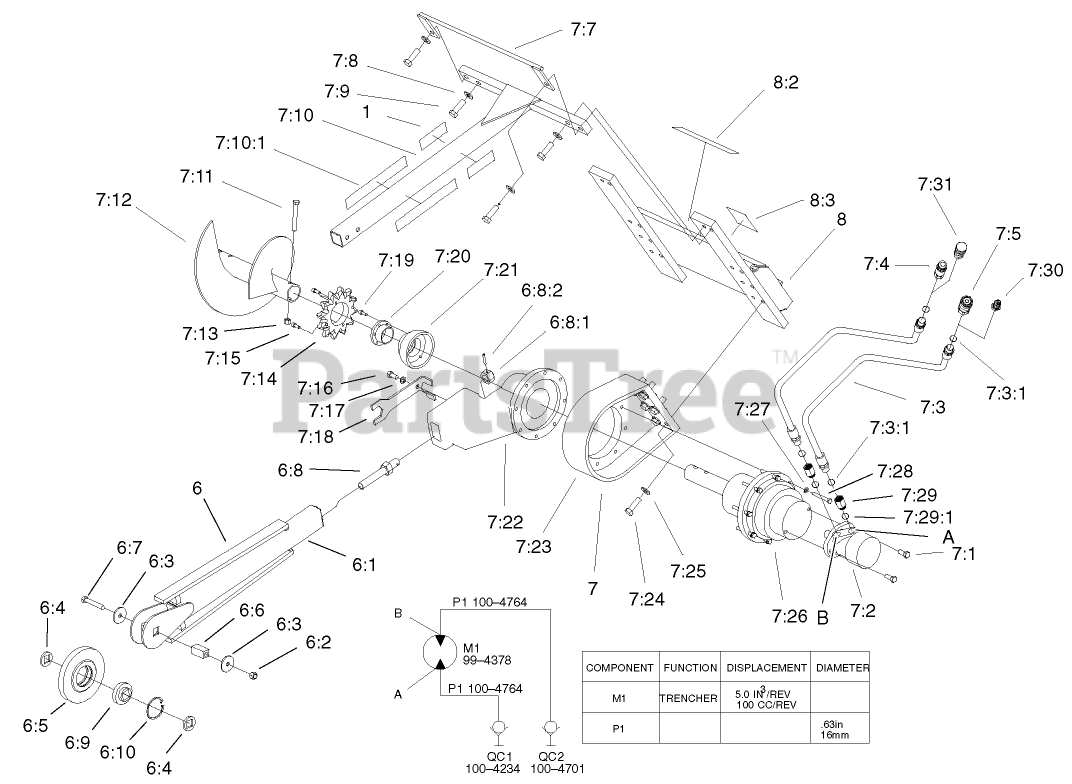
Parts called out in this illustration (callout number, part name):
1	DECAL-ATTACHMENT, DINGO
6	TRENCHER BOOM ASM
6:1	Boom ASM
6:2	NUT-LOCK
6:3	WASHER-ROLLER
6:4	SPACER-ROLLER
6:5	ROLLER-NOSE
6:6	PIN-ROLLER
6:7	SCREW-HH
6:8	ADJ SCREW ASM
6:8:1	NUT-HEX
6:8:2	PIN-ROLL
6:9	BEARING
6:10	RING-INT
7	Trencher Head ASM
7:1	SCREW-HH, LH
7:2	MOTOR-HYD(OPTIONAL), 100CC-1 INCH SHAFT
7:2	MOTOR-HYD, 80CC (1 INCH SHAFT)
7:3	HOSE-HYDRAULIC
7:3:1	O-RING
7:4	NIPPLE-CONNECT, PRESSURE
7:5	COUPLER-FACE, FLUSH
7:7	HOSE GUIDE ASM
7:8	WASHER-FLAT
7:9	SCREW-HH
7:10	SAFETY RAIL ASM
7:10:1	DECAL-DANGER
7:11	SCREW-HH
7:12	AUGER
7:13	NUT-LOCK, NI
7:14	SAND SPROCKET-12T
7:15	SCREW-HSH
7:16	SCREW-HH
7:17	WASHER-LOCK
7:18	SPANNER
7:19	SCREW-HSH
7:20	LOCK-TAPER
7:21	PROTECTOR-SEAL
7:22	MOUNT-BOOM
7:23	MOUNT-DRIVE, PLANETARY
7:24	SCREW-HH
7:25	WASHER-FLAT
7:26	GEARBOX ASM
7:27	WASHER-LOCK
7:28	SCREW-HH
7:29	ADAPTER-CONVERSION
7:29:1	O-RING
7:30	DISCONNECT-QUICK, MALE
7:31	DISCONNECT-QUICK, FEMALE
8	MOUNTING ASM
8:2	DECAL-DANGER
8:3	DECAL-DANGER
